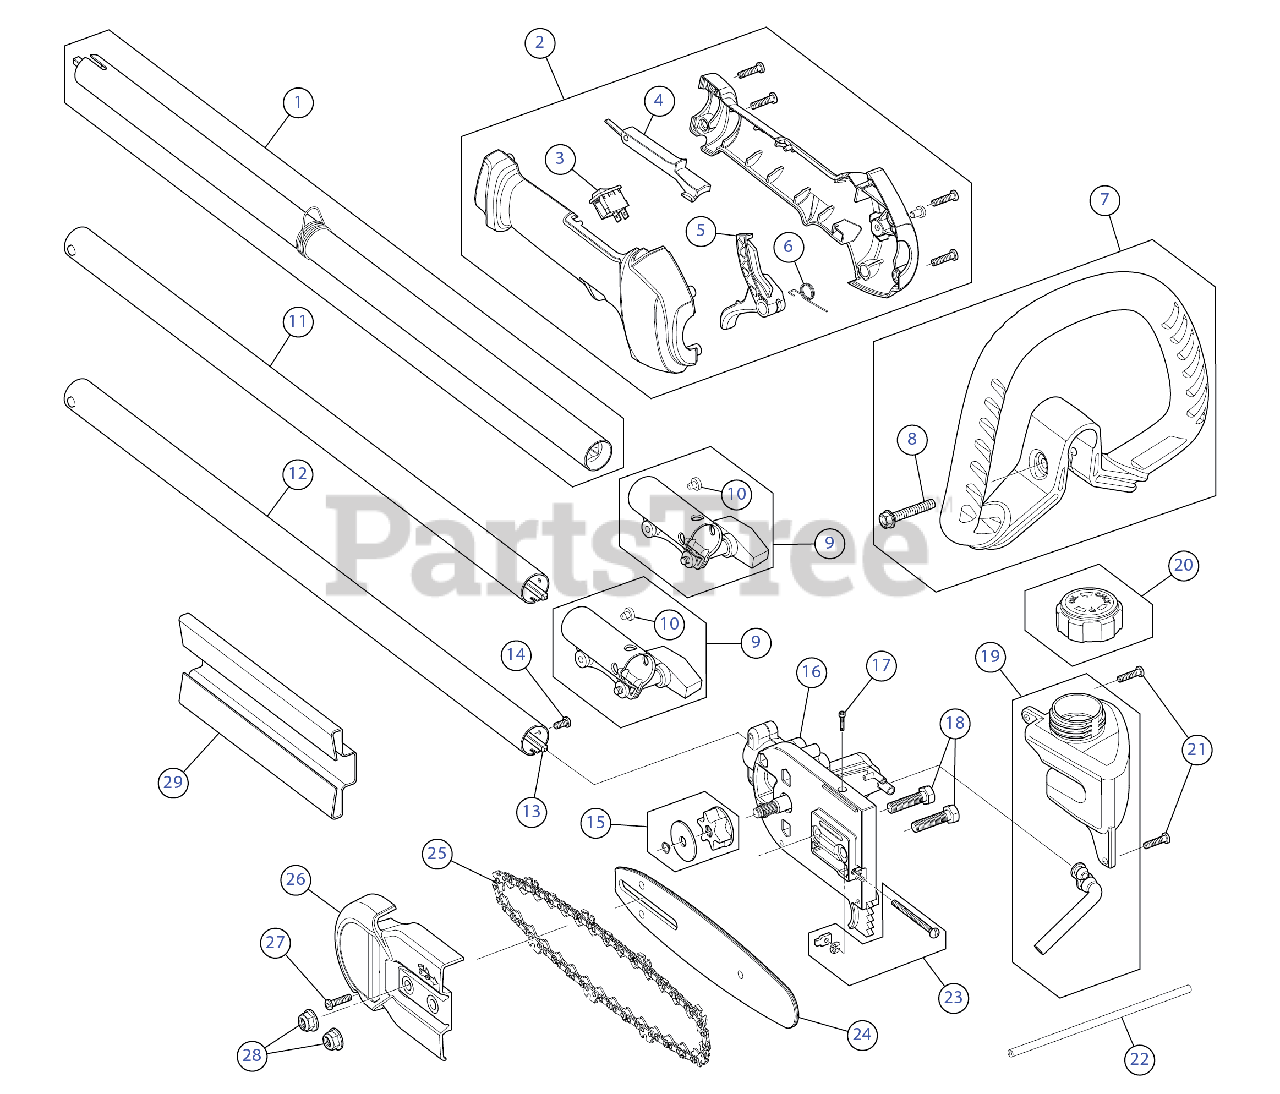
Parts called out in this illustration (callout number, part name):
1	BOOM ASSEMBLY UPR
2	THROTTLE GRIP ASSEMBLY
3	SW, MOMENTARY ON/O
4	LEVER LOCK OUT
5	THROTTLE TRIGGER
6	SPRING TRIG
7	HANDLE ASSEMBLY
8	BOLT 1/4-20X1 1/2
9	SPLIT BOOM CPLR
10	SCREW, 10-32X.250 TA
11	HOUSING ASSEMBLY UPPER W/FLEXSHAFT
12	BOOM ASSEMBLY 24"
13	LOWERIBLE DRIVE SHAFT
14	SCREW 1/4-20 X.500
15	SPROCKET ASSEMBLY
16	GEAR BOX ASSEMBLY
17	SCREW 4X40X.50
18	SCREW 5/16-18 x 1.25 GR5
19	OIL TANK ASSEMBLY
20	FUEL CAP ASSEMBLY
21	SCREW, #8-16X.750 PH
22	OIL LINE
23	CHAIN TENSION HDW
24	BAR 8" SPROCKET NOSE
25	CHAIN 8" 34 LINK .043 GAUGE
26	CHAIN GUARD
27	SCREW, #8-16X.750 PH
28	FLANGE LOCK NUT 5/16-18
29	CHAIN COVER
